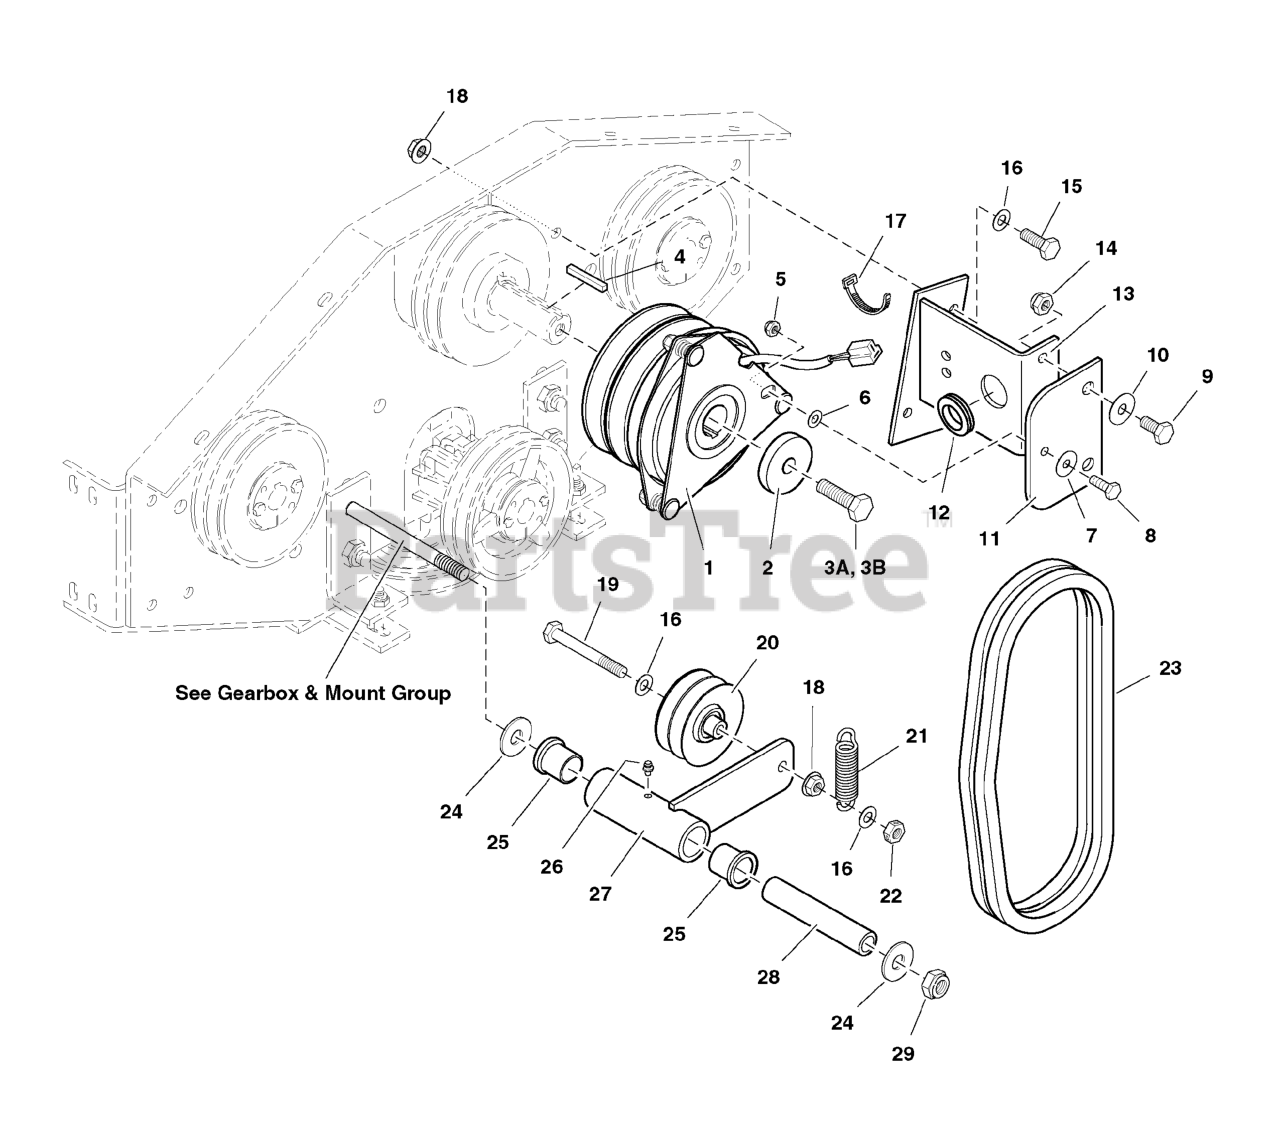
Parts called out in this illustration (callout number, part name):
1	KIT, CLUTCH & BOLT
2	SPACER, .45 x 1.88 x .38
3A	CRANKSHAFT BOLT, 7/16 x 1-1/2
3B	CRANKSHAFT BOLT, M10 x 70mm
4	KEY, 1/4 SQ. x 2
5	NUT, 5/16-24 HEX NYLON LOCK
6	WASHER, 5/16" SAE
7	WASHER, 5/16" Fender
8	BOLT, 5/16-18 X 1 GD5 YZ
9	BOLT, 3/8-16 X 1" GD5 CZ
10	WASHER, 3/8" Fender
11	CLUTCH ANCHOR PAD
12	GROMMET
13	CLUTCH ANCHOR
14	NUT, 3/8-16 HEX NYLON LOCK
15	BOLT, 3/8-16 X 1-1/4" GD5 CZ
16	WASHER, 3/8 SAE
17	TIE WRAP
18	NUT, 3/8-16 Hex Serrated Flange
19	BOLT, 3/8-16 X 3" GD5 CZ
20	PULLEY, Idler
21	SPRING, Extension
22	NUT, 3/8-16 Hex Side Lock
23	BELT, Clutch Drive (set of 2)
24	WASHER, 1/2 SAE
25	BUSHING, Flange
26	GREASE FITTING
27	CLUTCH DRIVE IDLER ARM
28	PIVOT SLEEVE, Long
29	NUT, 1/2-13 HEX NYLON LOCK
